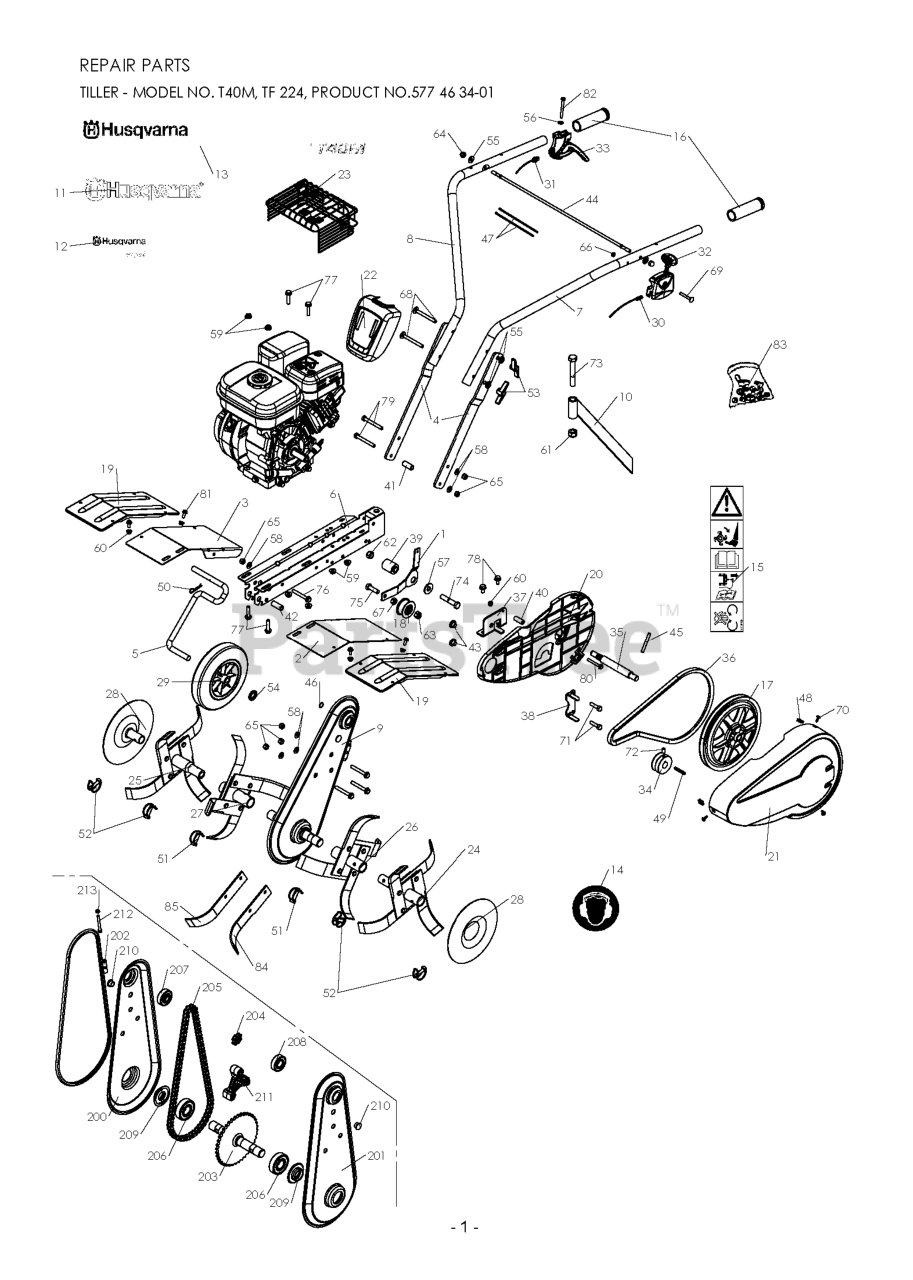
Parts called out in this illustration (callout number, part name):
46	RETAINING RING
50	COTTER PIN
66	Blocking nut M 6 Z
213	Blocking nut M 6 Z
